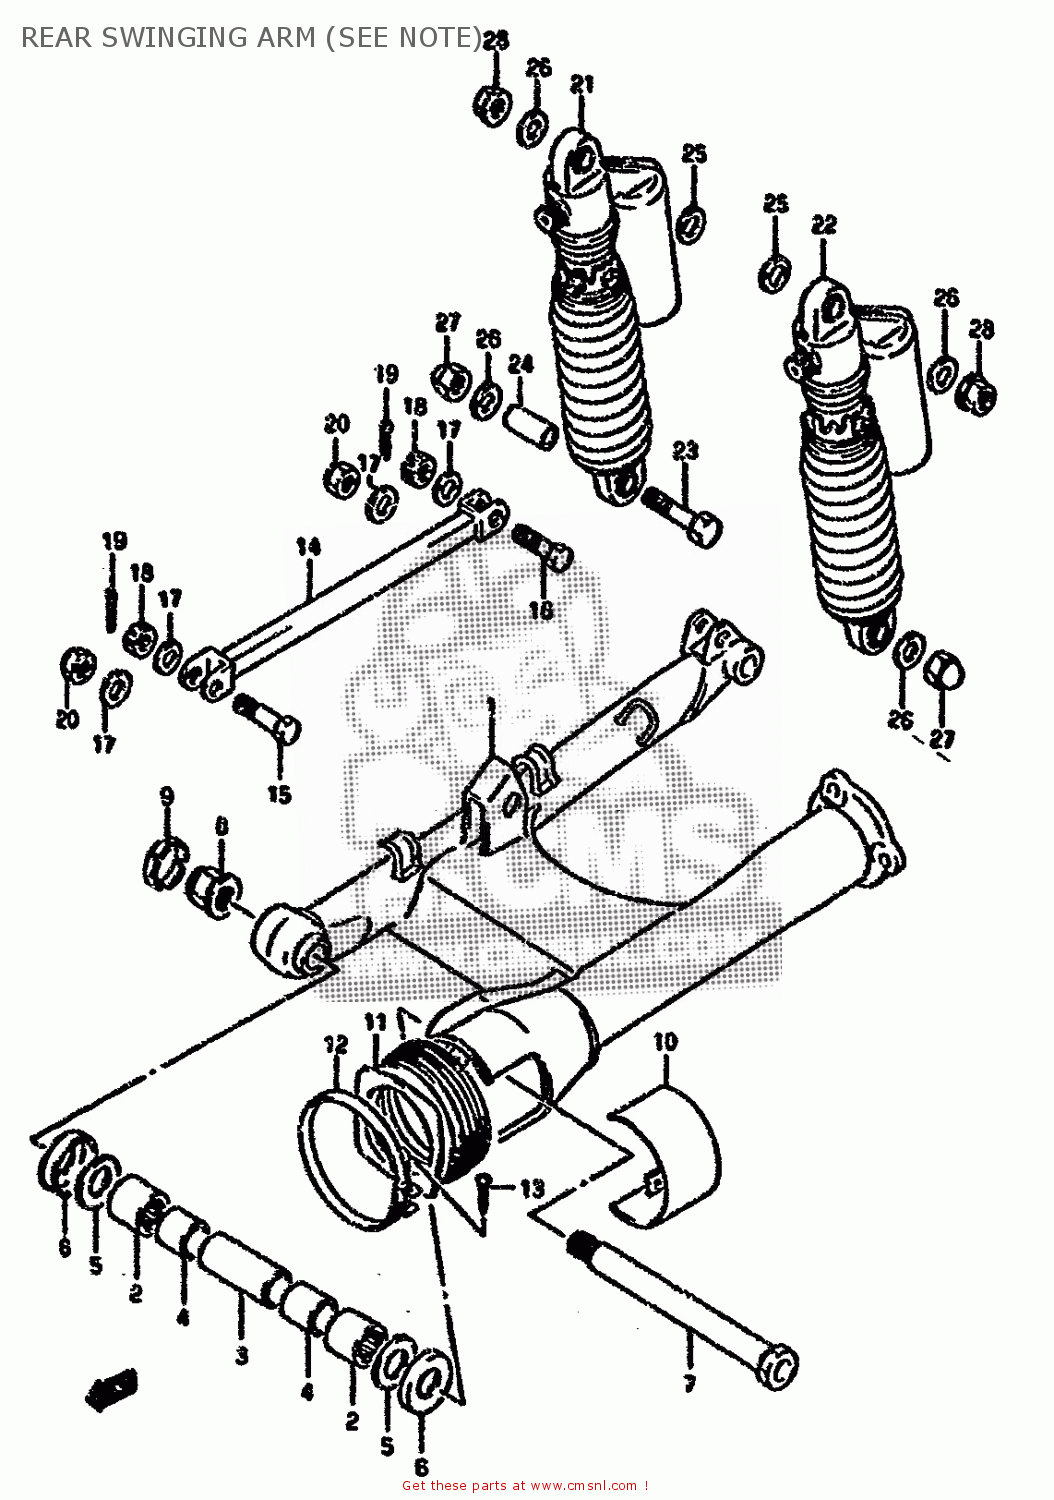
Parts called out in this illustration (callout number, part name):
1	SWING ARM ASSEMBLY,REAR
2	BEARING(25X33X30)
3	SPACER,REAR SWING ARM PIVOT
4	SPACER,RR SWGARM PIVOT BERRING
5	WASHER
6	COVER,RR SWGARM PIVOT SEAL
7	SHAFT,RR SWINGINGARM PIVOT
8	NUT ,18MM
9	CAP,RR SWINGING ARM PIVOT
10	COVER,RR SWGAR
11	BOOT,PROPELLER SHAFT
12	CLAMP
13	SCREW
14	TORQUE LINK,REAR
15	BOLT(10X41)
16	BOLT
17	WASHER
18	NUT
19	PIN 20X20
20	NUT
21	ABSORBER ASSY,RR SHOCK,R
22	ABSORBER ASSY,RR SHOCK,L
23	BOLT(10X39)
24	SPACER (10.2X14X20.7)
25	WASHER
26	WASHER
27	NUT
28	NUT
